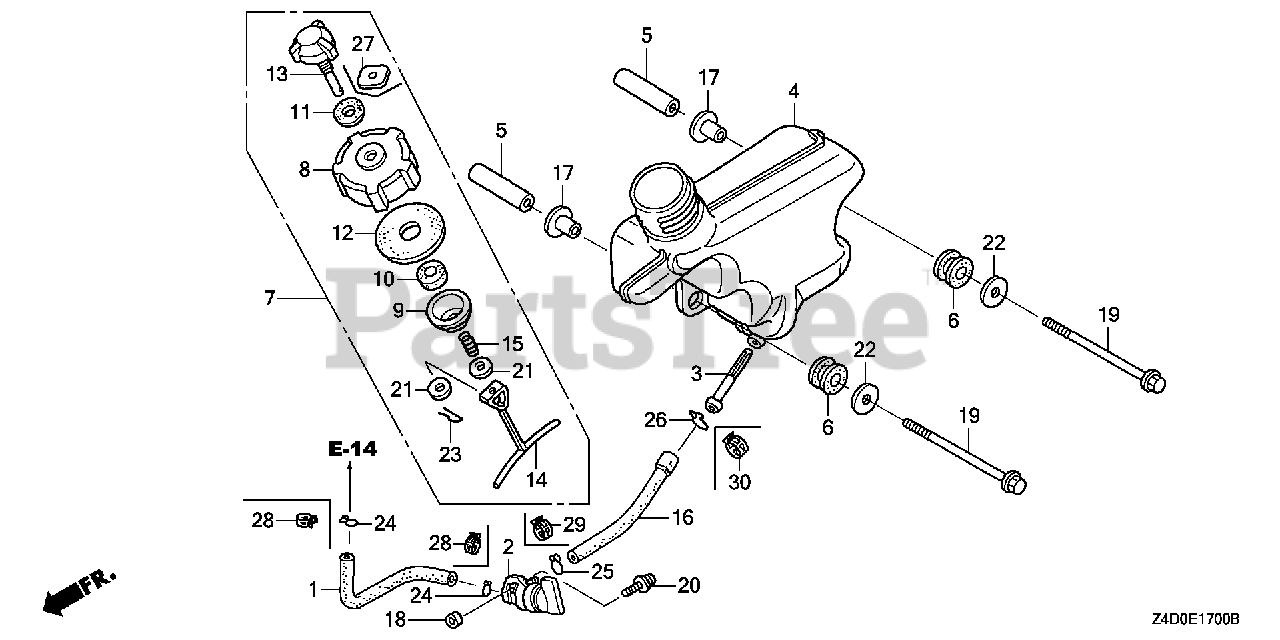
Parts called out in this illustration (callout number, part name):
1	TUBE B, FUEL
1	TUBE B, FUEL (FKM)
2	PETCOCK ASSY.
3	FILTER, FUEL
4	TANK, FUEL
4	TANK, FUEL (FOR U.S.A.)
5	COLLAR, TANK SETTING
6	RUBBER A, TANK MOUNTING
7	CAP ASSY., FUEL TANK
8	BODY, FUEL CAP
9	INNER, FUEL CAP
10	SPONGE, FUEL CAP BREATHER
11	GASKET, VALVE
12	GASKET, FUEL CAP
13	VALVE, BREATHER
14	LINK, FUEL CAP
15	SPRING, FUEL CAP
16	TUBE, FUEL TANK
16	TUBE, FUEL (FKM)
17	COLLAR, CANISTER MOUNTING
18	COLLAR, FR. TURN SIGNAL
19	BOLT, FLANGE (6X65)
20	SCREW-WASHER (5X10)
21	WASHER, PLAIN (4MM)
22	WASHER, PLAIN (6MM)
23	PIN, LOCK (4MM)
24	CLIP, TUBE (B8)
25	CLIP, TUBE (B10)
26	CLIP, TUBE (B12.5)
28	CLAMP, TUBE (D8)
29	CLAMP, TUBE (D10)
30	CLAMP, TUBE (D12)
